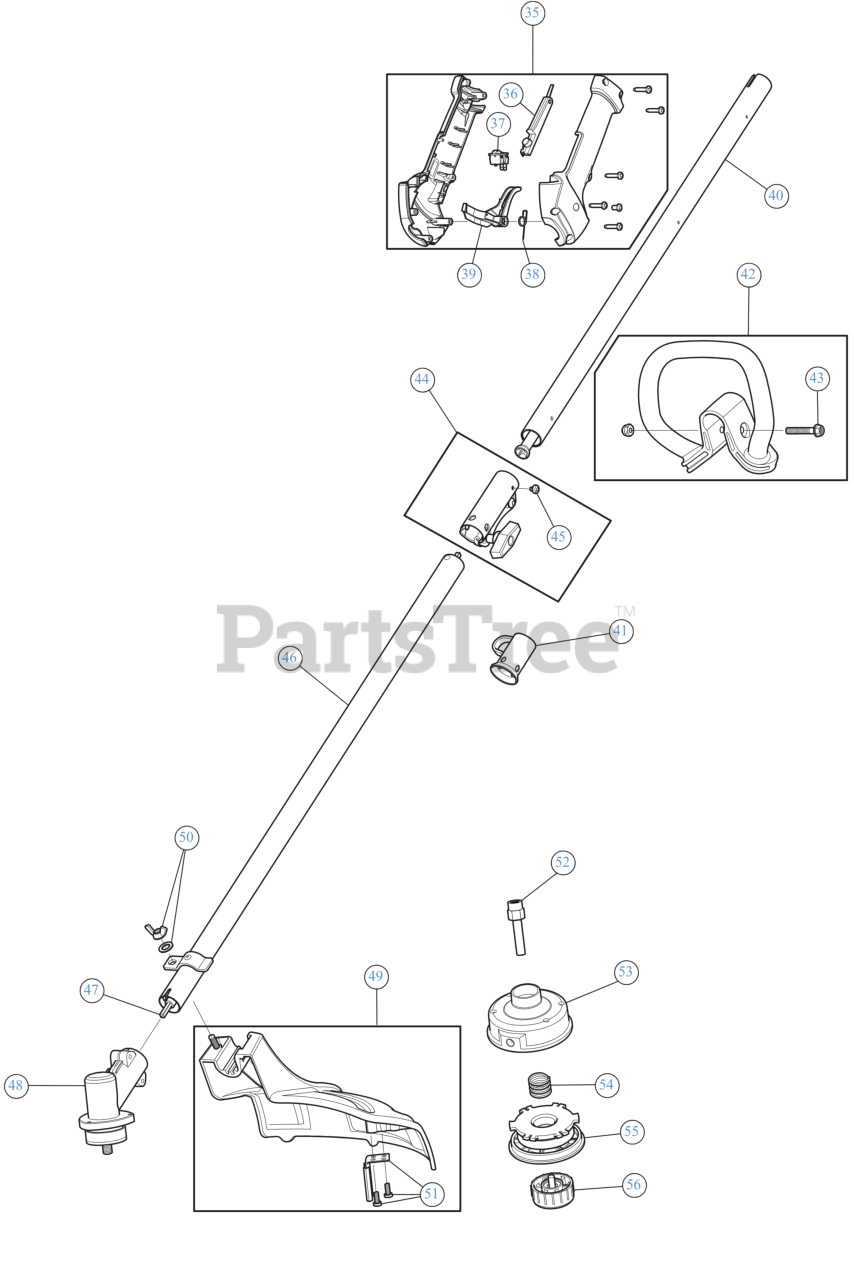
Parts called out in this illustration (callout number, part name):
35	THROTTLE GRIP ASSEMBLY
36	LEVER LOCK OUT
37	SW, MOMENTARY ON/O
38	SPRING TRIG
39	THROTTLE TRIGGER
40	BOOM ASSEMBLY UPR
41	HANGER
42	D-HANDLE
43	BOLT 1/4-20X1 1/2
44	COUPLER ASSEMBLY
45	SCREW, 10-32X.250 TA
46	LOWER BOOM ASSEMBLY
47	LOWER DRIVE SHAFT
48	GEARBOX
49	GUARD/BLADE ASM
50	BLADE GUARD MOUNTING HARDWARE
51	BLADE ASSEMBLY W/HDW
52	SHAFT ADAPTER
53	REEL:OTR W/RET
54	SPRING-SPOOL
55	INNER REEL
56	BUMP KNOB (BLACK)
